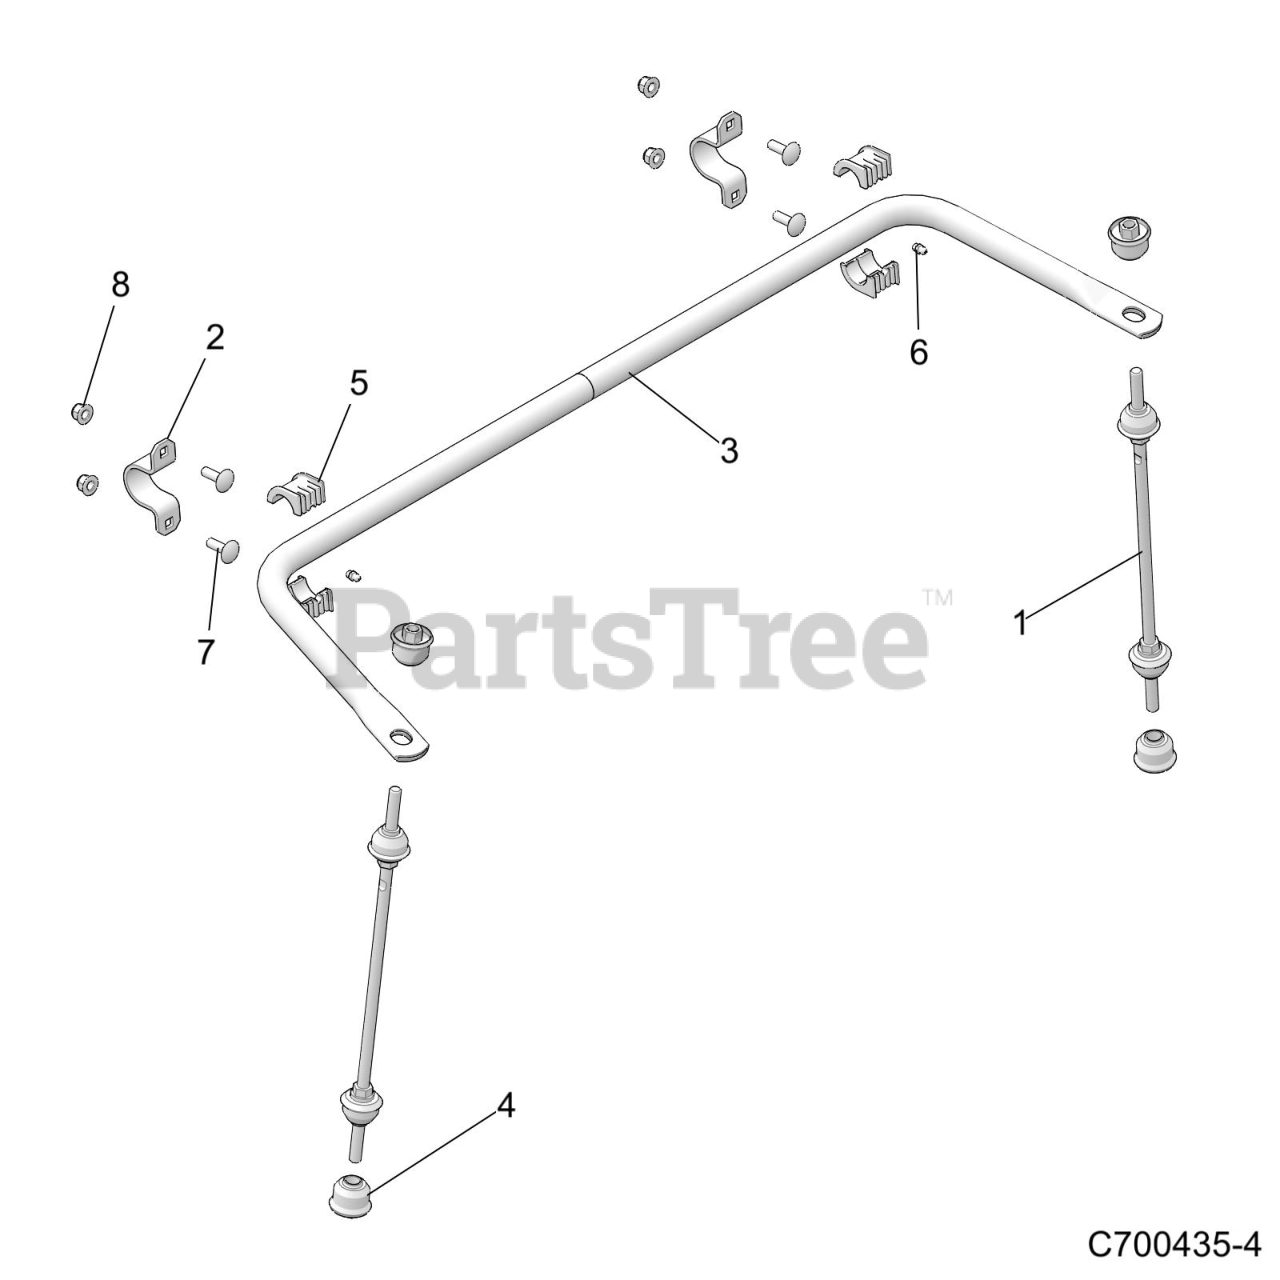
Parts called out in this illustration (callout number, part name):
1	ASM-LINKAGE,STABILIZER BAR
2	BRKT-BUSHING
3	TUBE-STABILIZER,M.BLK
4	BUSHING-LNKG TORBAR,DURO80
5	BUSHING-UPPER STEERING,1 IN
6	FITTING-LUB,1/4-28-STR/1792-Y
7	SCR-RHCAR-M8X1.25X25 10.9 ZB3
8	NUT-M8X1.25,FLG,NYLOC-OLIVE D
